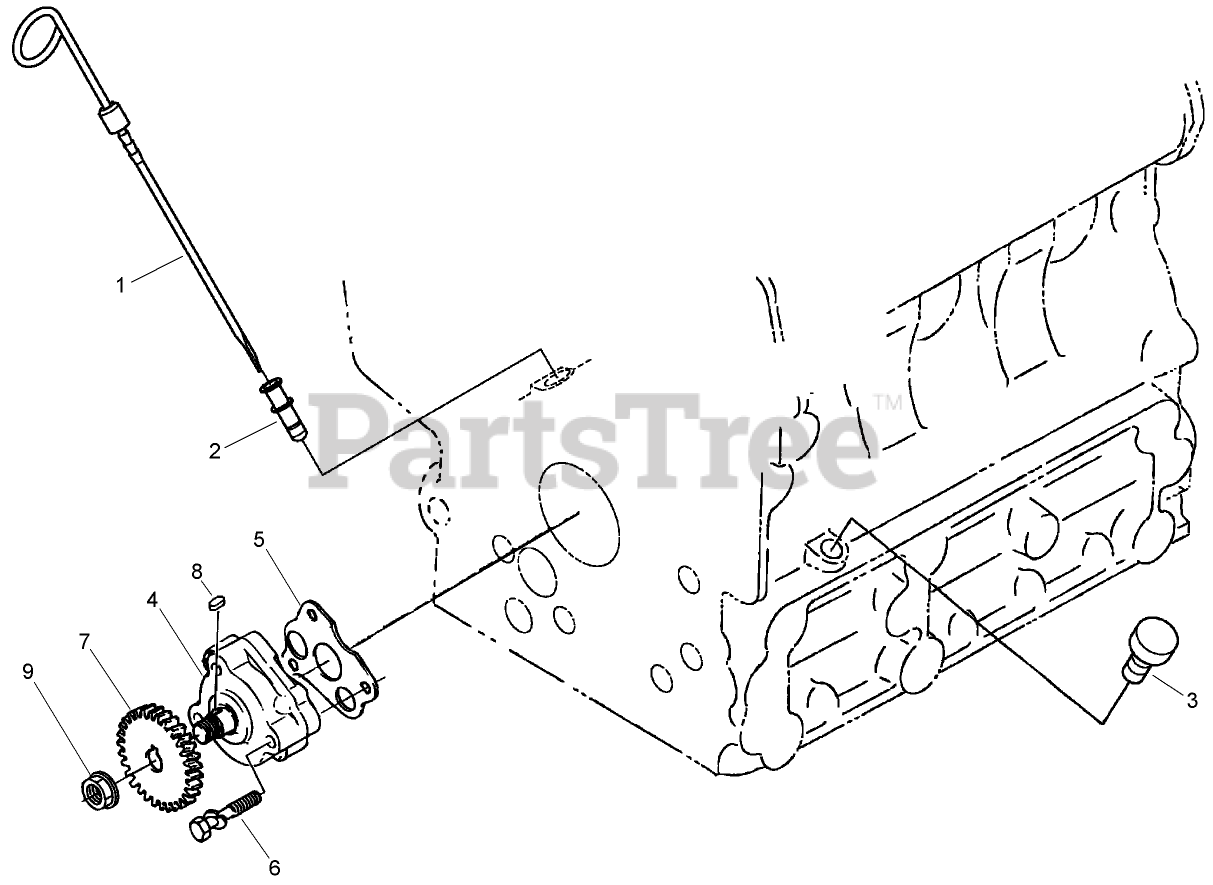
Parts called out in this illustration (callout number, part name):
1	GAUGE-OIL
2	GUIDE-GAUGE, OIL
3	PLUG-GAUGE, OIL
4	OIL PUMP ASM
5	GASKET-PUMP, OIL
7	GEAR-DRIVE, OIL PUMP
8	KEY-FEATHER
9	NUT-FLANGE
